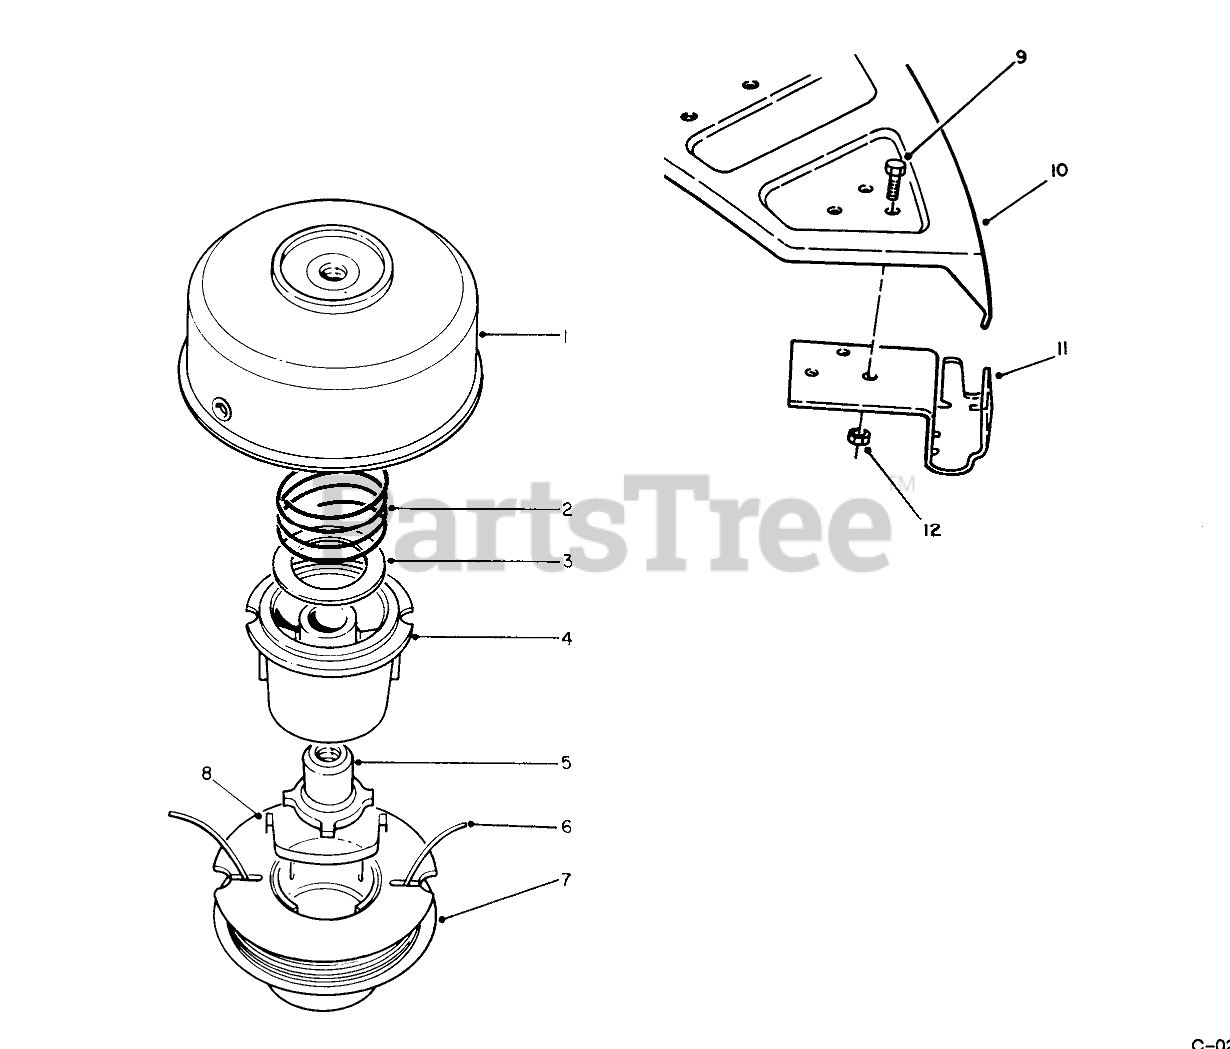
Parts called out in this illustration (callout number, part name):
1	ASM - TRIMMER DRUM & EYELET
2	SPRING
3	WASHER-FLAT
4	SPOOL CORE
5	LH DRIVER
6	REPL LINE PKG
7	Spool Prewound (Incl. Ref. #8)
8	SADDLE-SPOOL CAP
9	SCREW-SHH
10	Shield-Grass
11	BRACKET & KNIFE ASM
12	NUT-LOCK, NI
